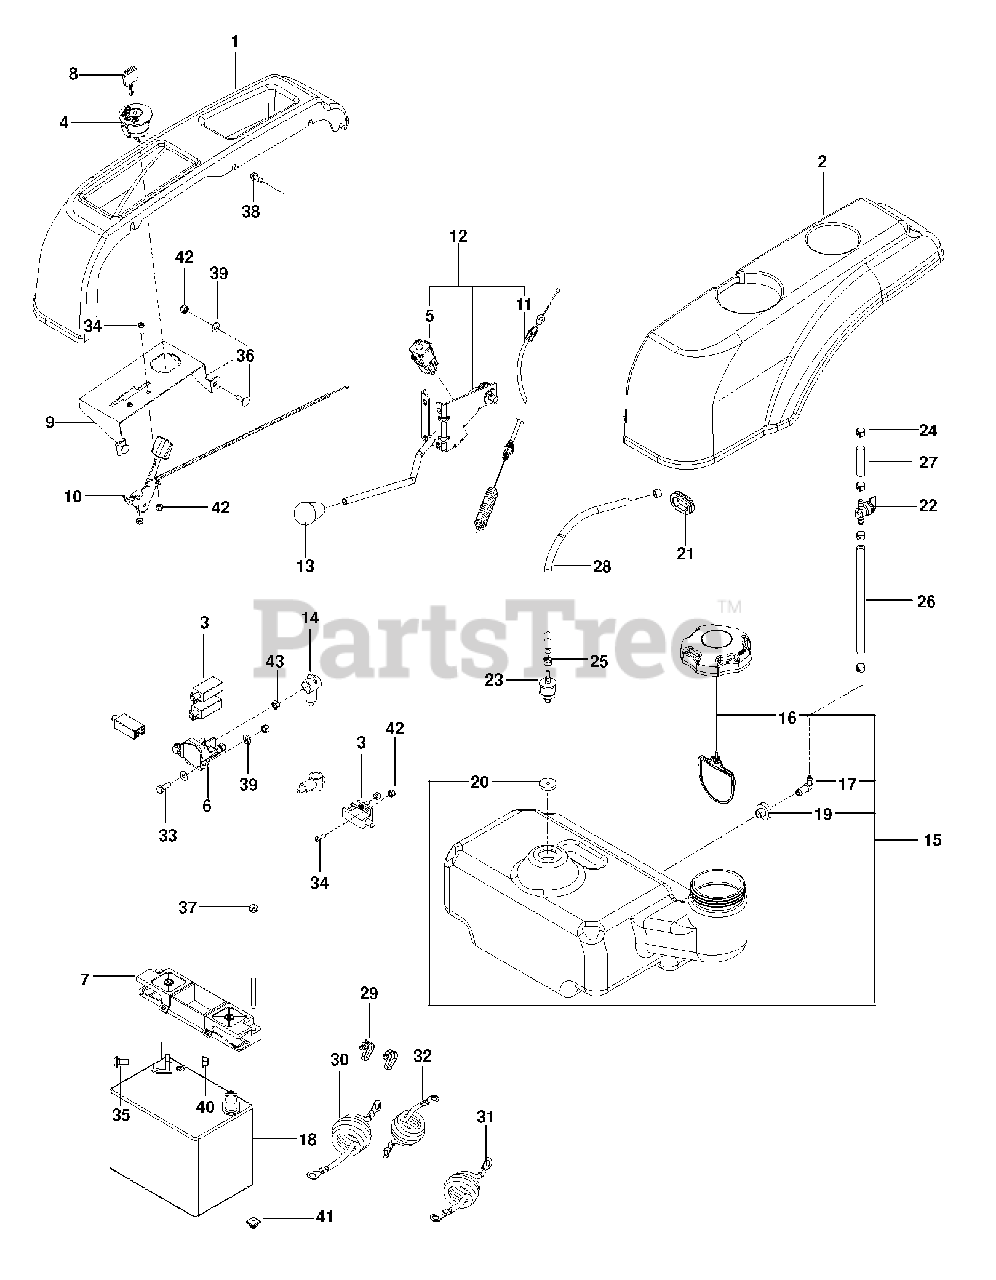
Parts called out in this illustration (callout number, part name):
1	FENDER RH
2	FENDER LH
4	IGNITION SWITCH
5	SWITCH INTERLOOK PUSH-IN
6	SOLENOID
7	BATTERY HOLD DOWN
9	CONTROL PANEL MT.
10	THROTTLE CABLE
11	CABLE.CLUTCH.38".SERVICE
12	ASM, CLUTCH ENGAGE W/CABLE
13	KNOB - SHIFT
14	TERMINAL COVER-SM
15	FUEL TANK ASM SMALL
16	CAP, FUEL
19	RUBBER GROMMET
20	GROMMET, CHECK VALVE
22	FUEL VALVE
23	VALVE.FUEL.CHECK
24	HOSE CLAMP
25	CLAMP, HOSE
26	HOSE 1/4 X 8
27	HOSE 1/4 X 2"
28	HOSE, FUEL, 3/16" X 20"
29	TIE WRAP, 8-3/8", W/CLIP
30	POST.CABLE LONG
31	CABLE POSITIVE, LONG
32	BATTERY CABLE, NEGATIVE
33	HCS 1/4C X 3/4 HCS
34	SCREW #10-24 X 5/8
35	BOLT 5/16C X 3/4" CARRIAGE
36	RHSNB 1/4C X 3/4
37	BOLT - 1/4-20 X 7.5
38	SCREW 1/4 X 5/8
39	WASHER 1/4 SAE
40	5/16-18 NYLOC FLANGE NUT
41	PUSH NUT-NYLON
42	NUT 10-24 NYLOC
43	NUT 1/4-20 NYLOC
